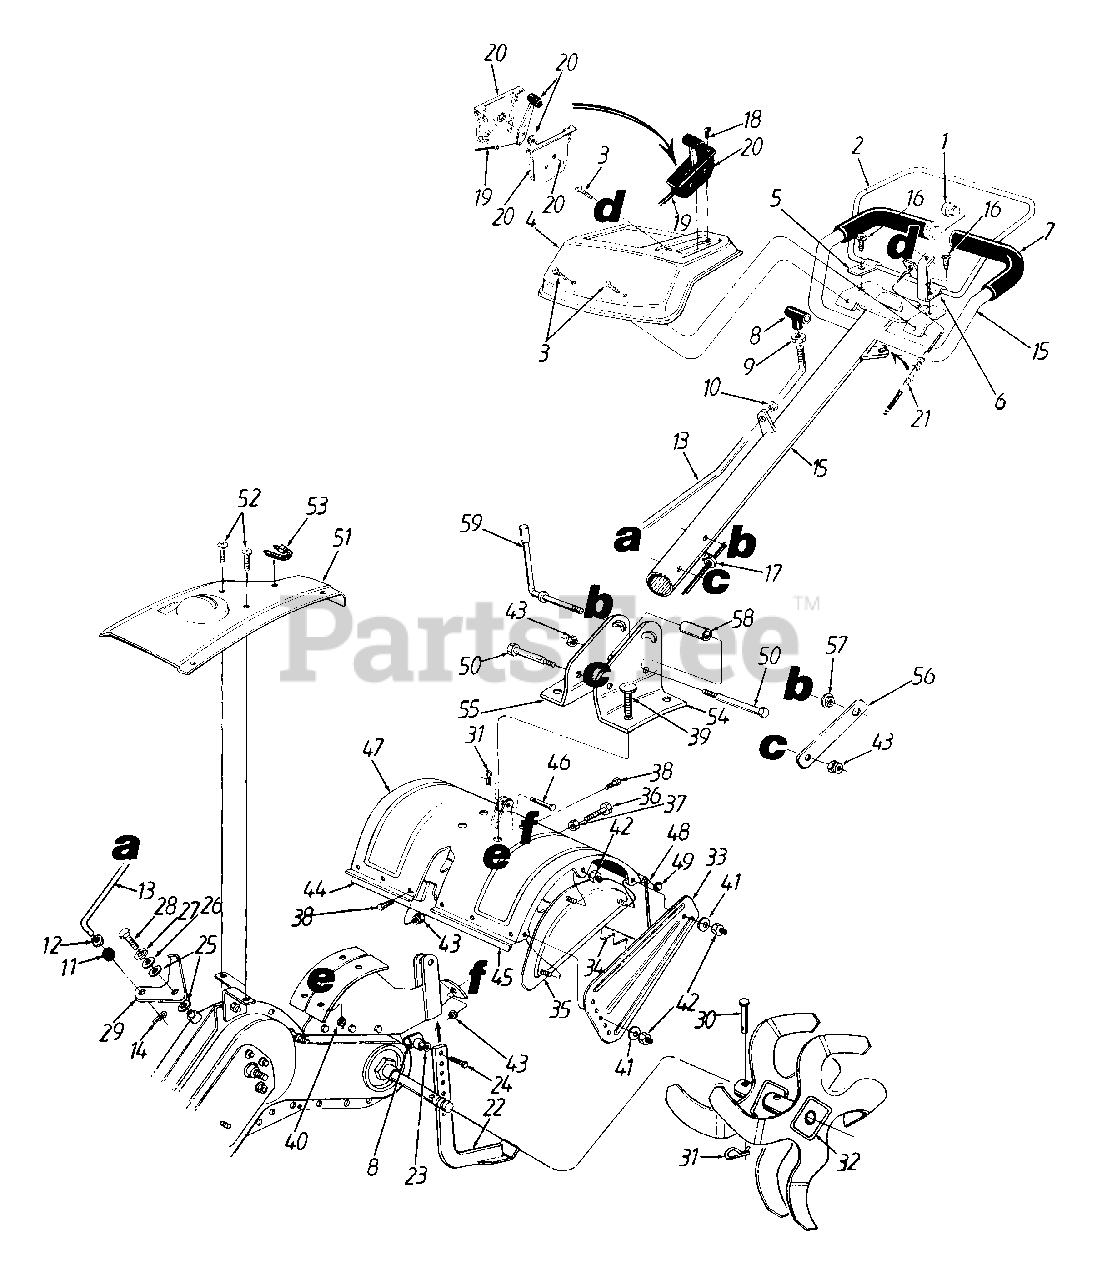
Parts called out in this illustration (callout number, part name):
1	Vinyl End Plug
3	Torx Mach. AB-Tap Scr. 1/4 x .62" Lg.
7	Grip
9	Hex Jam Nut 3/8-16 Thd.
10	Bushing 3/8" I.D.
11	Rubber Washer
12	Fl-Wash. .344" I.D. x .6" O.D.
13	Gear Shift Rod
14	Hairpin Clip
17	Cable Clip
18	Truss Mach. AB-Tap Scr. #10 x .5" Lg.
19	Throttle Wire 55" Lg.
20	Throttle Control Box Ass'y.
21	Clutch Cable
23	Fl-Wash. 3/8" I.D. x 5/8" O.D.
24	Hex Bolt 3/8-16 x .75" Lg.
25	Washer 1" O.D. (Hdn.)
26	Fl-Wash. .281" I.D. x .73" O.D.
27	L-Wash. 1/4" I.D.
28	Hex Bolt 1/4-20 x .62" Lg. (Gr. 5)
29	Shift Brkt.
30	Clevis Pin
31	Hairpin Clip
36	Hex Cap Bolt 5/16-18 x 1.25" Lg.
37	Hex Nut 5/16-18 Thd.
38	Hex Bolt 5/16-18 x .75" Lg.
39	Carriage Bolt 3/8-16 x 1" Lg.
40	Hex Ins. L-Nut 3/8-16 Thd.
41	Bell-Wash. .345" I.D. x .88" O.D.
42	Hex Cap L-Nut 5/16-18 Thd.
43	Hex Flange Top L-Nut 5/16-18 Thd.
46	Clevis Pin .375" Dia.
49	Cap Speed Nut
50	Hex Bolt 5/16-18 x 3" Lg.
52	Torx Mach. AB-Tap Scr. 1/4 x .6"
53	Wire Retainer Clip
57	Hex Flange Nut 3/8-24 Thd.
58	Spacer .322 Dia.
59	Handle Adjustment Crank
